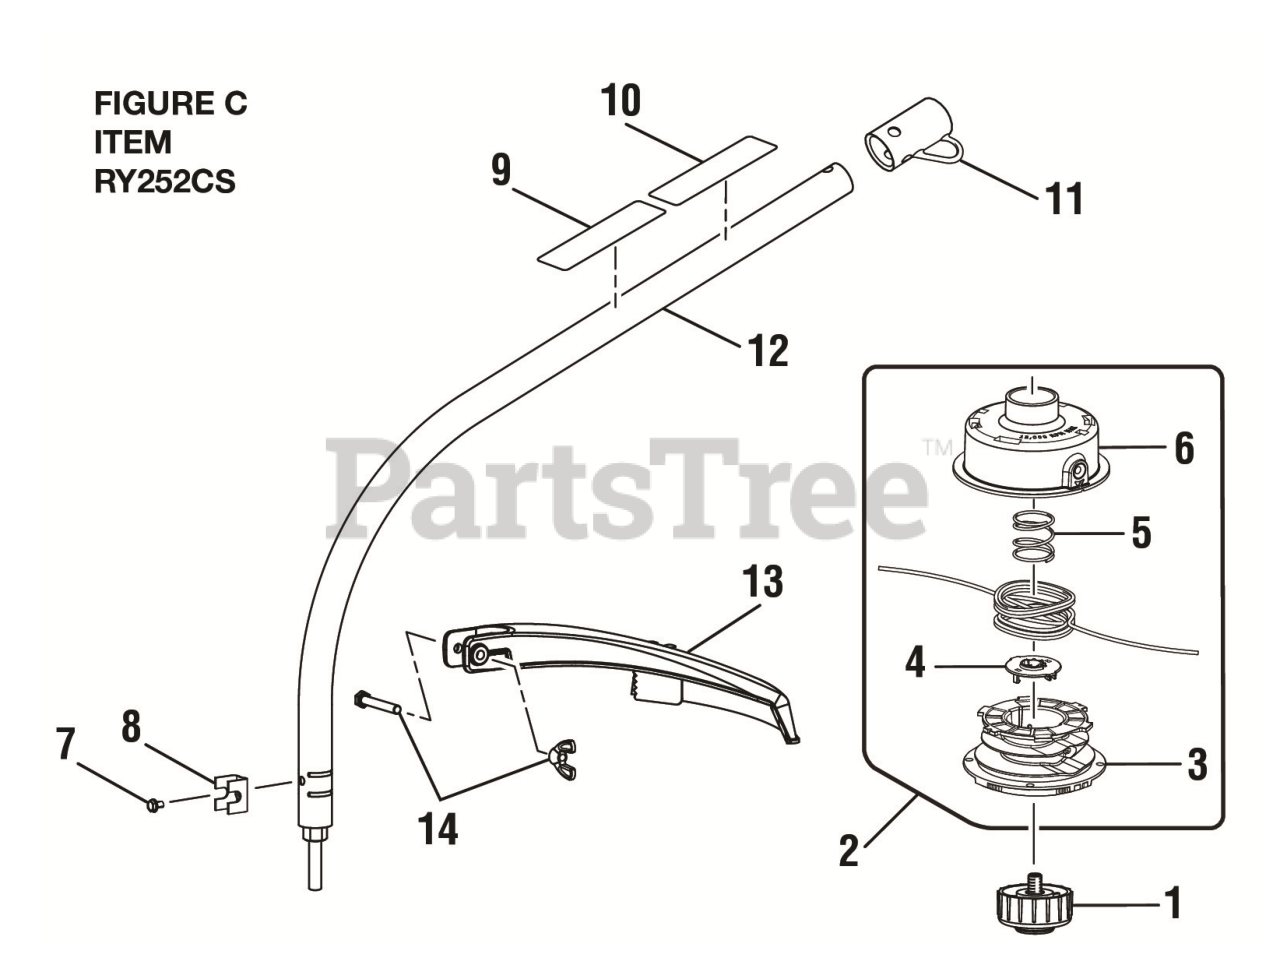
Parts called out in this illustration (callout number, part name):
1	RETAINING CAP, LEFT-HANDED THREAD
2	Reel Easy String Cutting Head Assembly
3	Spool Assembly
4	String Guide
5	Compression Spring
6	Housing and Eyelet Assembly
7	Screw (#10-32 x 3/8 in., Hex Washer Hd. S.T.)
9	Ryobi EXPAND-IT Label
10	Warning Icon Label
11	Storage Hanger Cap
12	Curved Shaft Assembly
13	Grass Deflector Assembly
14	Fastener Parts Kit
